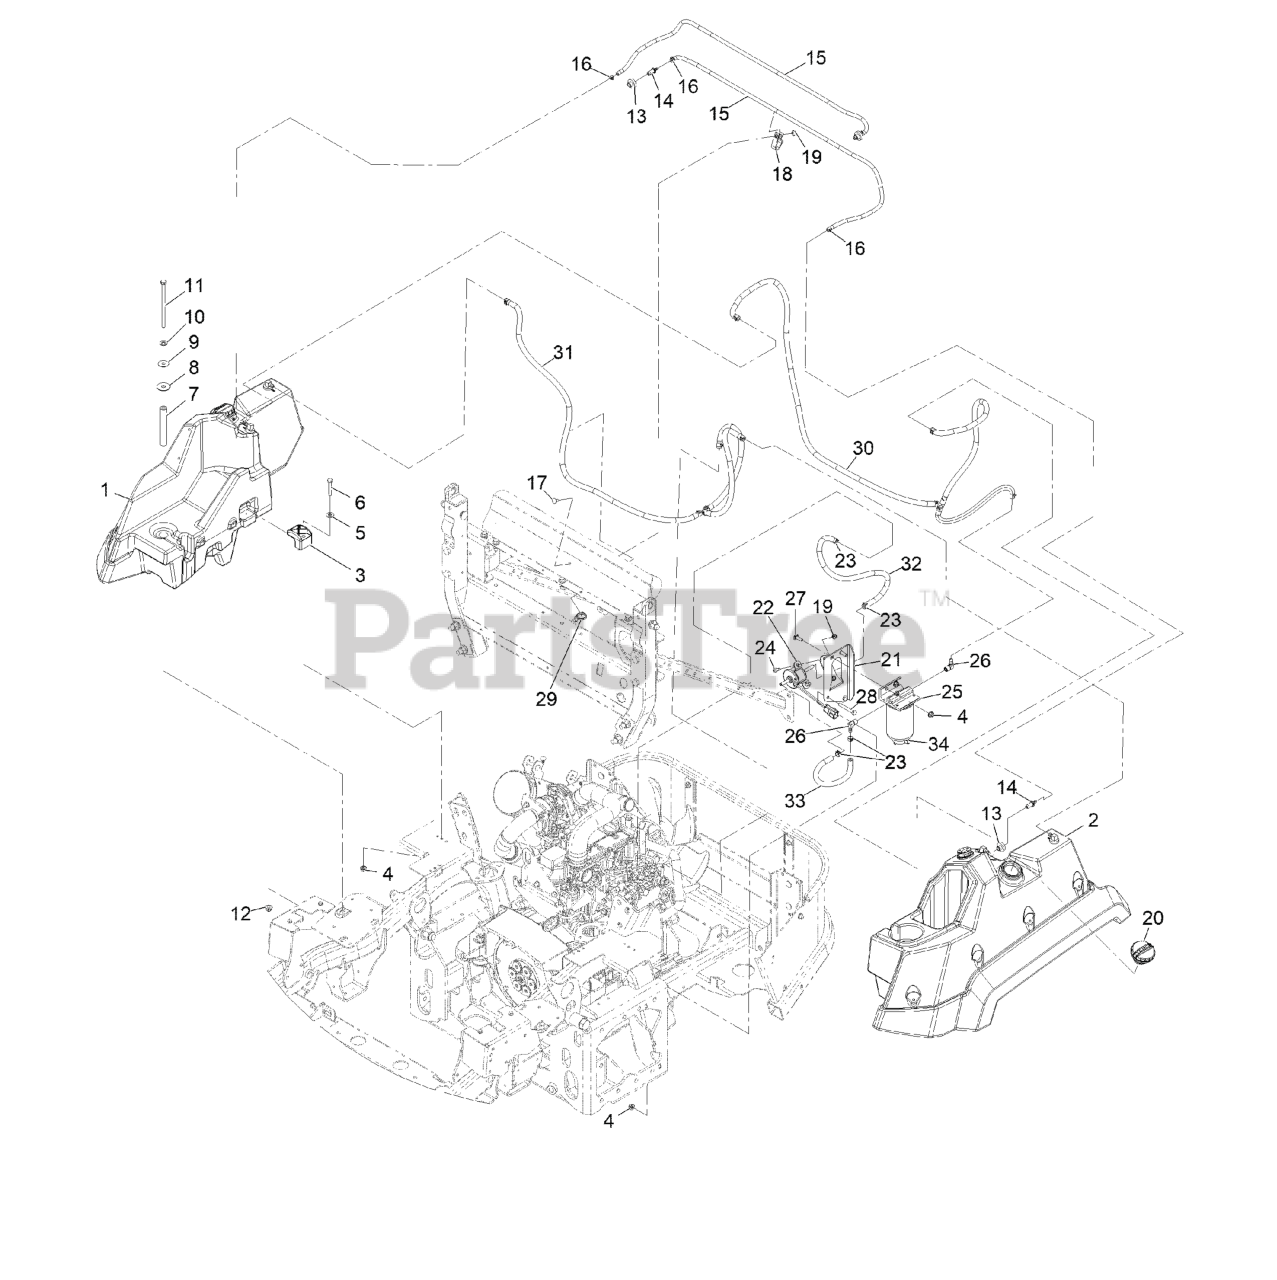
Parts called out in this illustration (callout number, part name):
1	RH FUEL TANK ASM
2	LH FUEL TANK ASM
4	NUT-HF, NI
5	WASHER-FLAT
6	SCREW-HH
7	TUBE-SPACER
8	WASHER-RUBBER
9	WASHER-PLAIN
10	WASHER-FLAT
11	SCREW-HH
12	NUT-HF, NI
13	BUSHING
14	FITTING-ORIFICE, STRAIGHT
15	HOSE-VENT, TANK
16	CLAMP-HOSE
17	SCREW-CARR
18	CLAMP-HOSE
20	CAP-FUEL, DIESEL
21	BRACKET-FILTER AND PUMP,
22	PUMP-FUEL, ELECTRIC
23	CLAMP-HOSE
24	SCREW-HWH
25	ASM,FUEL FILTER W/HEAD
26	FITTING-HYD, 90
27	SCREW-CARR
28	SCREW-HH
29	CLIP-TIE
30	LINE-FUEL, SUCTION
31	LINE-FUEL, RETURN
32	HOSE-FUEL
33	HOSE-FUEL
34	FILTER-FUEL
